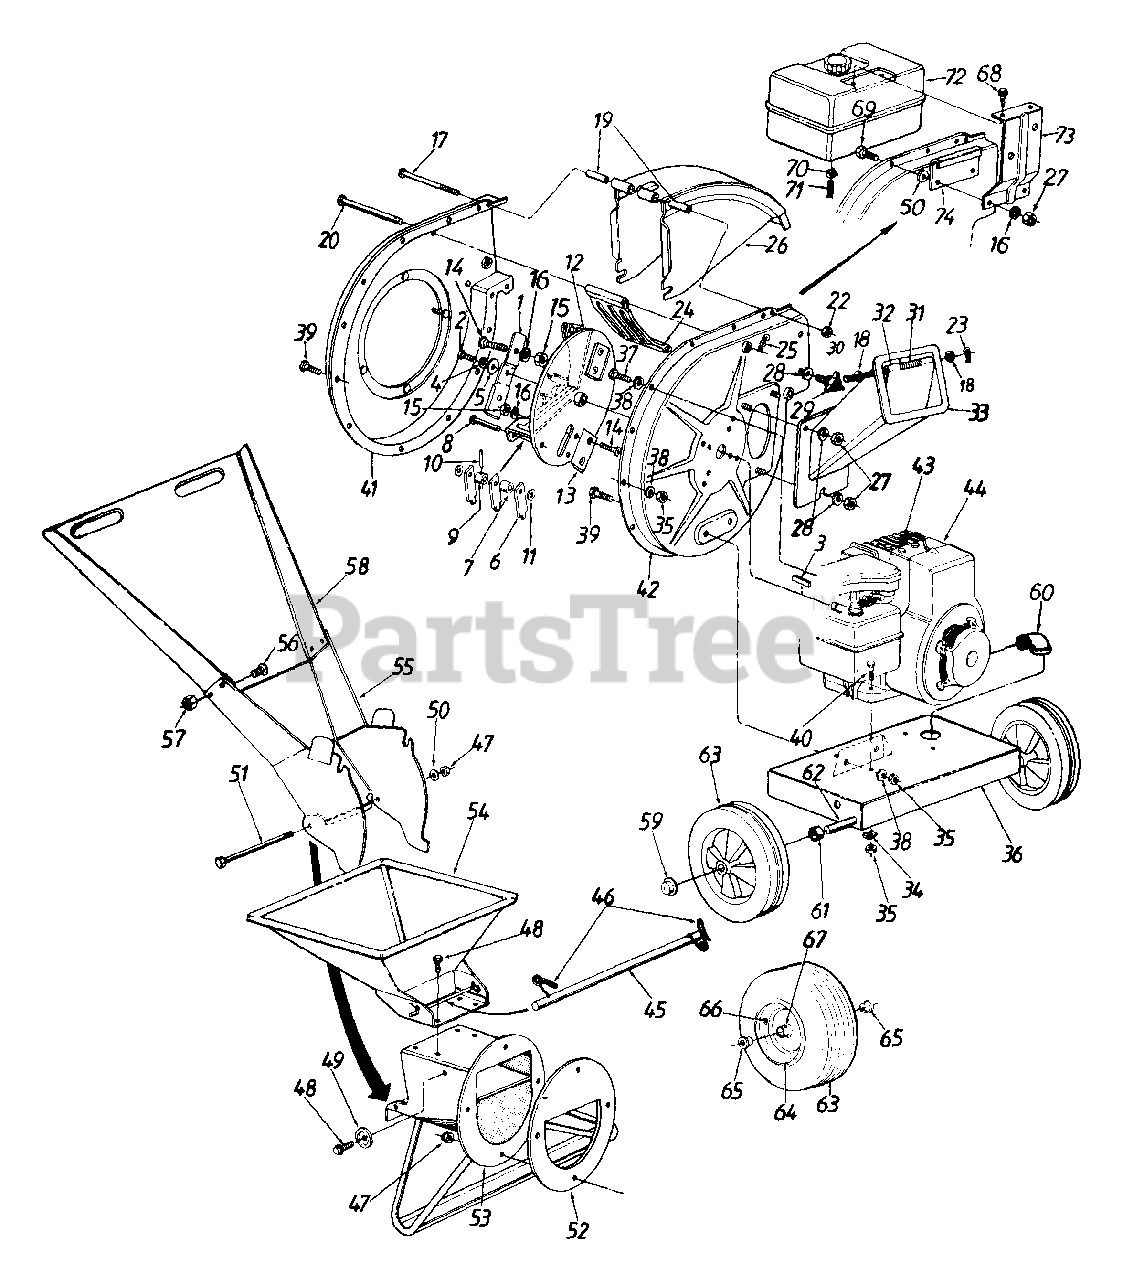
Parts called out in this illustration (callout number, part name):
1	Blade
2	Hex Patch Bolt 3/8-24 x 2" Lg. (Gr. 8)
3	Sq. Key 1/4 x 2.0" Lg.
4	L-Wash. 3/8" I.D. H.D.
5	Fl- Wash..406" I.D. x 1.25" O.D.Hdn.
6	Flail
7	Flail Spacer
8	Clevis Pin .496" Dia.
9	Flail Spacer w/.160" Dia. Hole
10	Spring Roll Pin 1.12" Lg.
11	Fl-Wash..531" I.D. x .94" O.D.
12	Impeller Ass'y. Comp.
13	Chipper Blade
14	Flat Hd. Scr. 5/16-24 x .75" Lg.
15	Hex Top L-Nut 5/16-24 (Gr. 5)
16	L-Wash. 5/16" I.D.
17	Hex Bolt 1/4-20 x 3.75" Lg.
18	Fl-Wash..281" I.D. x .5" O.D.
19	Chute Hinge Spacer 1.66" Lg.
20	Clevis Pin .5" Dia. x 4.62" Lg.
22	Hex Ctr. L-Nut 1/4-20 Thd.
23	Cotter Pin 3/32" x 5/8"
25	Internal Cotter Pin 3/8" Dia.
27	Hex Nut 5/16-18 Thd. (Gr. 5)
28	Bell-Wash..345" I.D. x .88"
29	Hand Knob
30	Chipper Door Rod
31	Torsion Spring 1.14" Lg.
35	Hex Nut 5/16-18 Thd. (Gr. 5)
38	L-Wash 5/16" I.D
39	Hex Bolt 5/16-18 x 75" Lg.
40	Hex Bolt 5/16-18 x 1.75" Lg.
44	Engine
45	Release Bar
46	Torsion Spring 1.06" Lg.
47	Elastic Lock Nut 5/16-18 Thd.
48	Hex Wash. Hd. Self-Tap Scr. 5/16-18 x .75" Lg.
49	Stop Washer
50	Fl-Wash 5/16" I.D.
51	Hex Bolt 5/16-18 x 8.38" Lg.
57	Hex L-Nut 1/4-20 Thd.
60	Drain Elbow (5 HP B & S)
61	Spacer .64" I.D. x .38" Lg.
62	Shredder Axle
63	Wheel Ass'y. Comp. (Plastic-10 x 2.5)
64	Rim Only
65	Flange Bearing .632" I.D.
66	Air Valve
67	Grease Fitting
68	Hex Hi-Low Scr. 1/4 x .75"
69	Hex Bolt 5/16-18 x .88" Lg.
70	Hose Clamp
71	Fuel Line-7 in.
72	Fuel Tank Ass'y. Comp.
